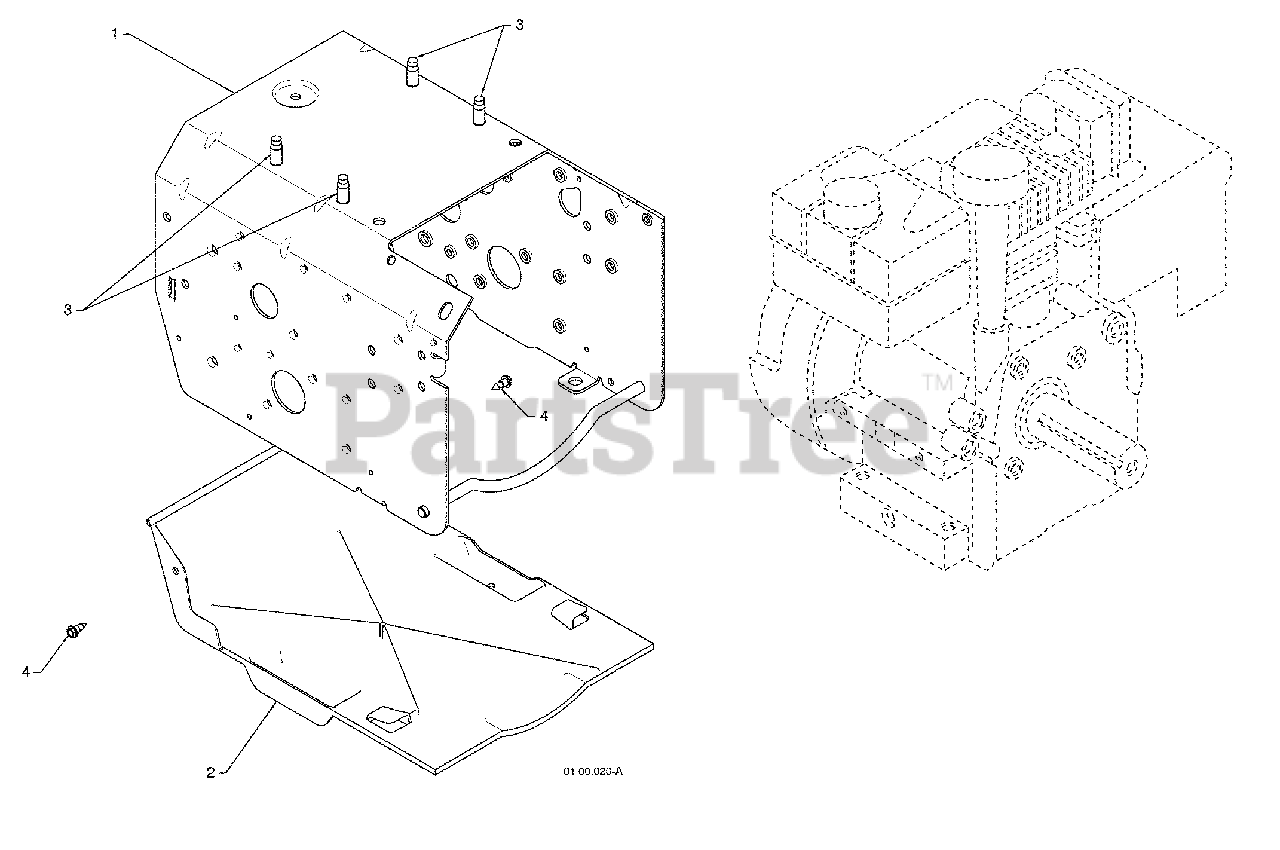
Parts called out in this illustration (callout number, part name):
1	FRAME
2	BOTTOM PAN
3	BOLT 3/8-16
4	SCREW 10-24 X .625
